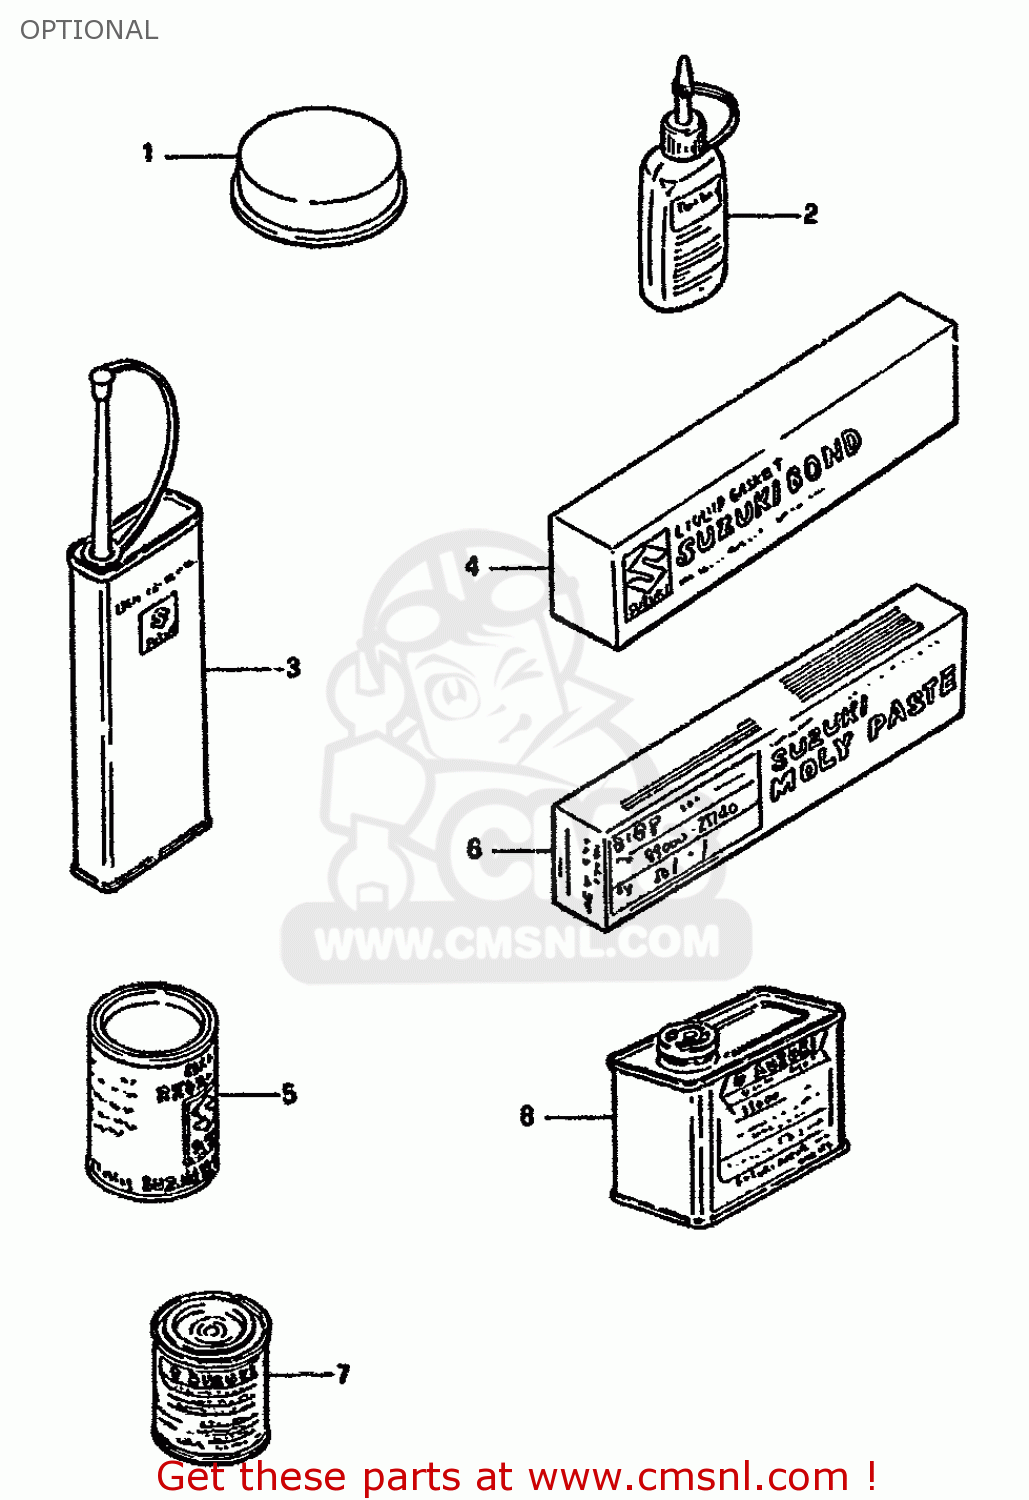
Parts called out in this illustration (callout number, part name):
1	GREASE,PBC FOR BRK PAD 20G
2	THREAD LOCK NO.1342
3	THREAD LOCK NO.1401 CLEAR 200G
4	LIQUID GSKT NO.1215 250G
5	GREASE(C)EP2 LITHIUM 150G
6	SUZUKI MOLY PASTE
7	PAINT,BLACK
8	PAINT (BLACK)
